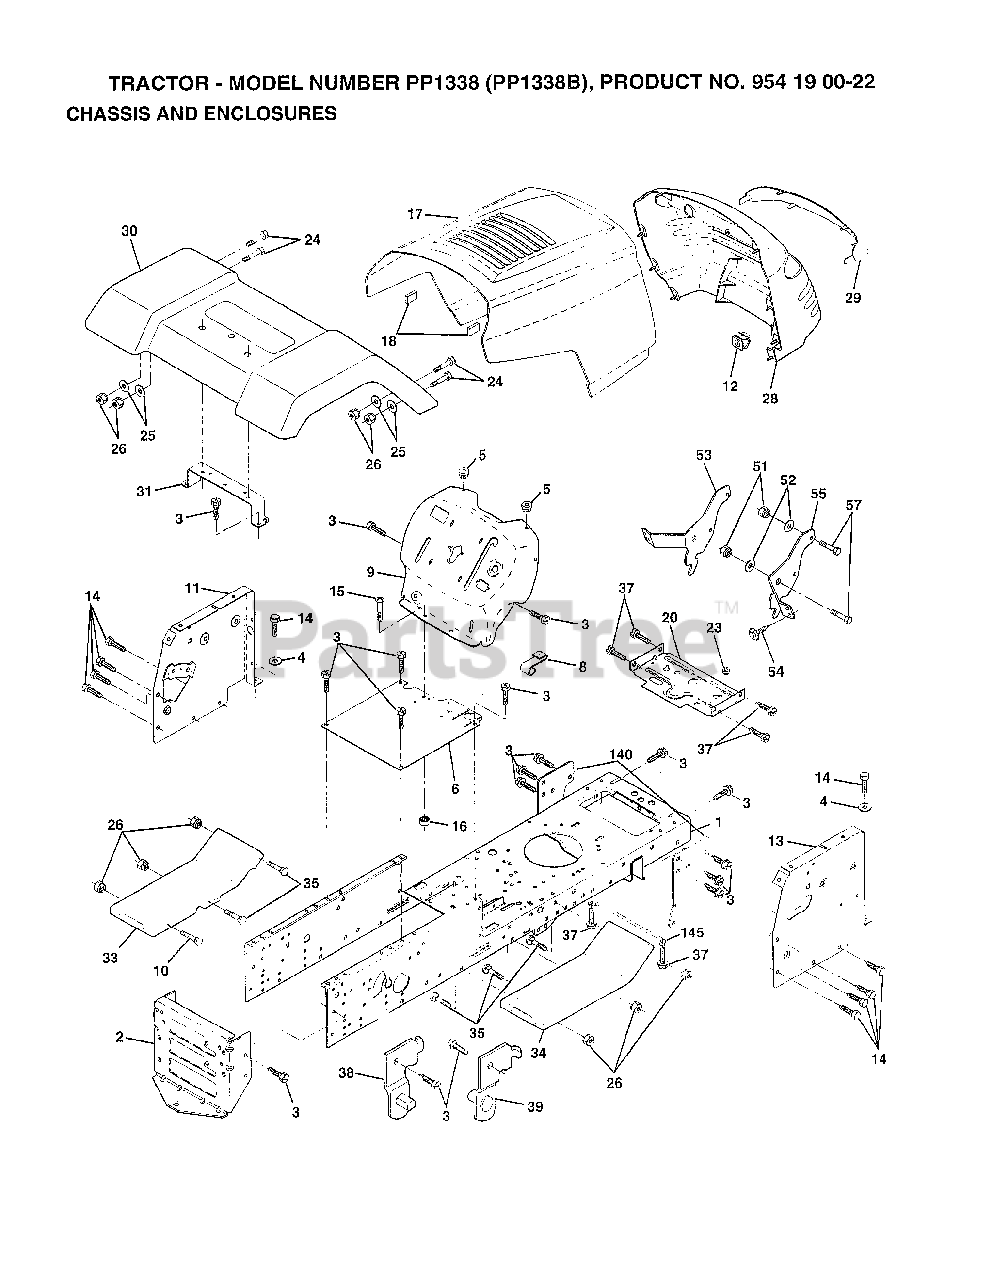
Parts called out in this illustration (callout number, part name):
3	SCREW
4	WASHER
5	BUMPER-HOOD/DASH
6	SADDLE
8	CLIP.RETAINER
9	DASH SILKSCREEN
11	"PANEL-DASH,LH"
12	CLIP.TINNERMAN
13	"PANEL-DASH,RH"
14	SCREW LT
15	SCREW
17	"HOOD W/TRIM,MS428"
20	"PLATE-MTG,BATT/FU"
24	BOLT
25	WASHER
26	NUT
28	GRILLE-MS428
29	LENS GRILLE
30	FENDER.LT.W/SHIFT
31	BRKT FENDER
33	FOOTREST.LH.LT/GT
34	FOOTREST.RH.LT/GT
35	BOLT
38	BRACKET ASM LH
39	BRACKET ASM RH
51	NUT
52	WASHER
53	BRACKET.GRILLE.LH
54	SCREW.HEX.WS.HD
55	BRACKET.GRILLE.RH
140	BRKT SUSPENSION
145	"ROD POVOT,CHASSIS"
